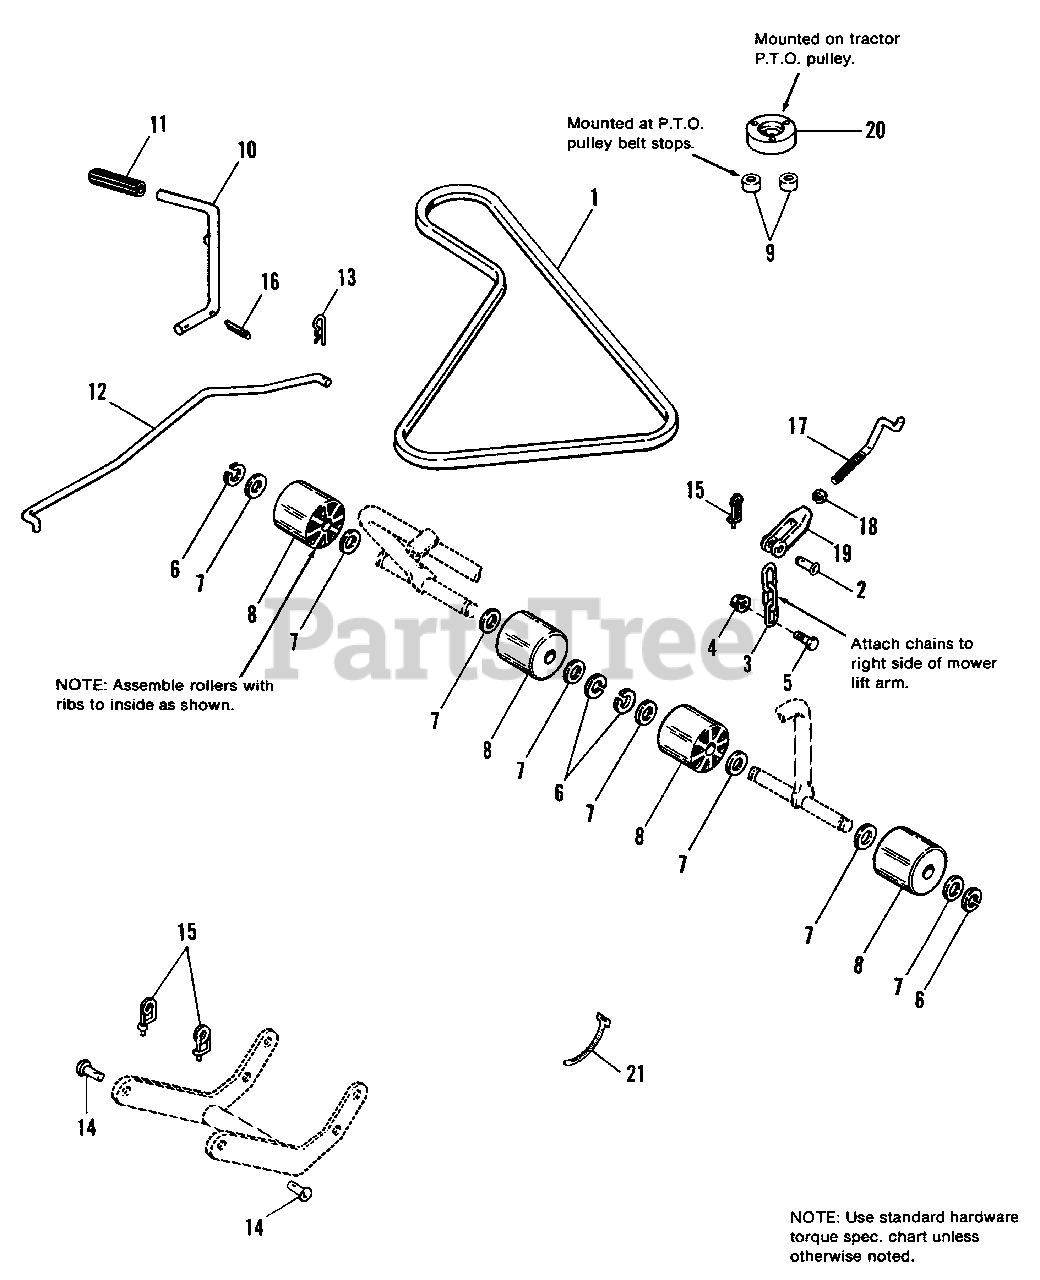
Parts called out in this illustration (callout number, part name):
1	V-BELT, Mower Drive
2	PIN, Rivet
3	CHAIN, Lift
4	LOCKNUT, Hex, Flange, 5/16-18
5	CAPSCREW, Hex Hd., 5/16-18 x 1
6	RING, Retaining
7	WASHER, Plain, 5/8
10	LEVER, Control
11	GRIP, Handle
12	ROD, P.T.O.
13	CLIP, Spring
15	CLIP, Pin, Safety
16	PIN, Cotter, 1/8 x 1
17	ROD, Lift (Incl. Ref. No. 15, 18, 2 & 19)
18	NUT, Jam, 5/16-18
20	SPACER, Pulley
21	TIE, Self-Locking
